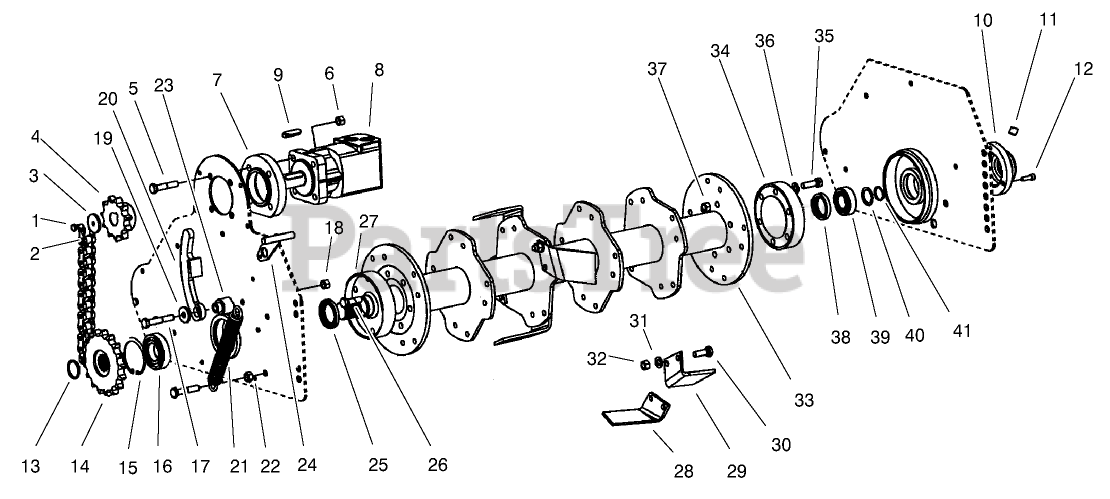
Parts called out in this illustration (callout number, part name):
1	SCREW-HH
2	CHAIN-ROLLER
3	WASHER
4	GEAR-11 TOOTH
5	SCREW-HH
6	NUT-LOCK
7	WASHER-FIXING, MOTOR
8	MOTOR-HYD
9	KEY-MOTOR
10	CAP-END
11	PLUG-BRASS
12	BOLT-HSH
13	CIRCLIP
14	GEAR-17 TOOTH
15	CIRCLIP
16	BEARING ASM
17	SCREW-HH
18	NUT-LOCK
19	WASHER-FLAT
20	TIGHTENER-CHAIN
21	SPRING-EXTENSION
23	BRACING-TUBULAR
24	HANDLE-SPRING
25	RING-PACKING
27	SHAFT-DRIVE
28	BLADE-LEFT
29	BLADE-RIGHT
30	BOLT-HH
31	WASHER-LOCK
32	NUT-HEX
35	SCREW-HH
36	WASHER-LOCK
37	NUT-HEX
38	RING-PACKING
39	BEARING ASM
40	WASHER
41	CIRCLIP
